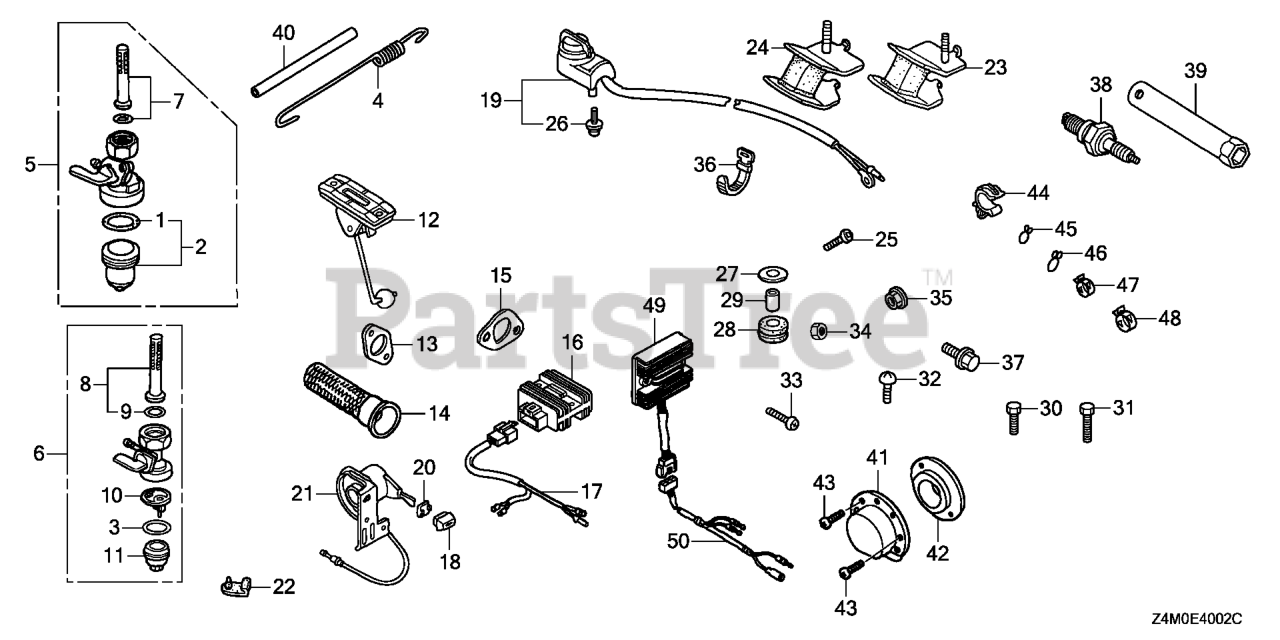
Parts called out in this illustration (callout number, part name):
41	DEFLECTOR
42	GUIDE, MUFFLER
43	SCREW, TAPPING (4X8)
